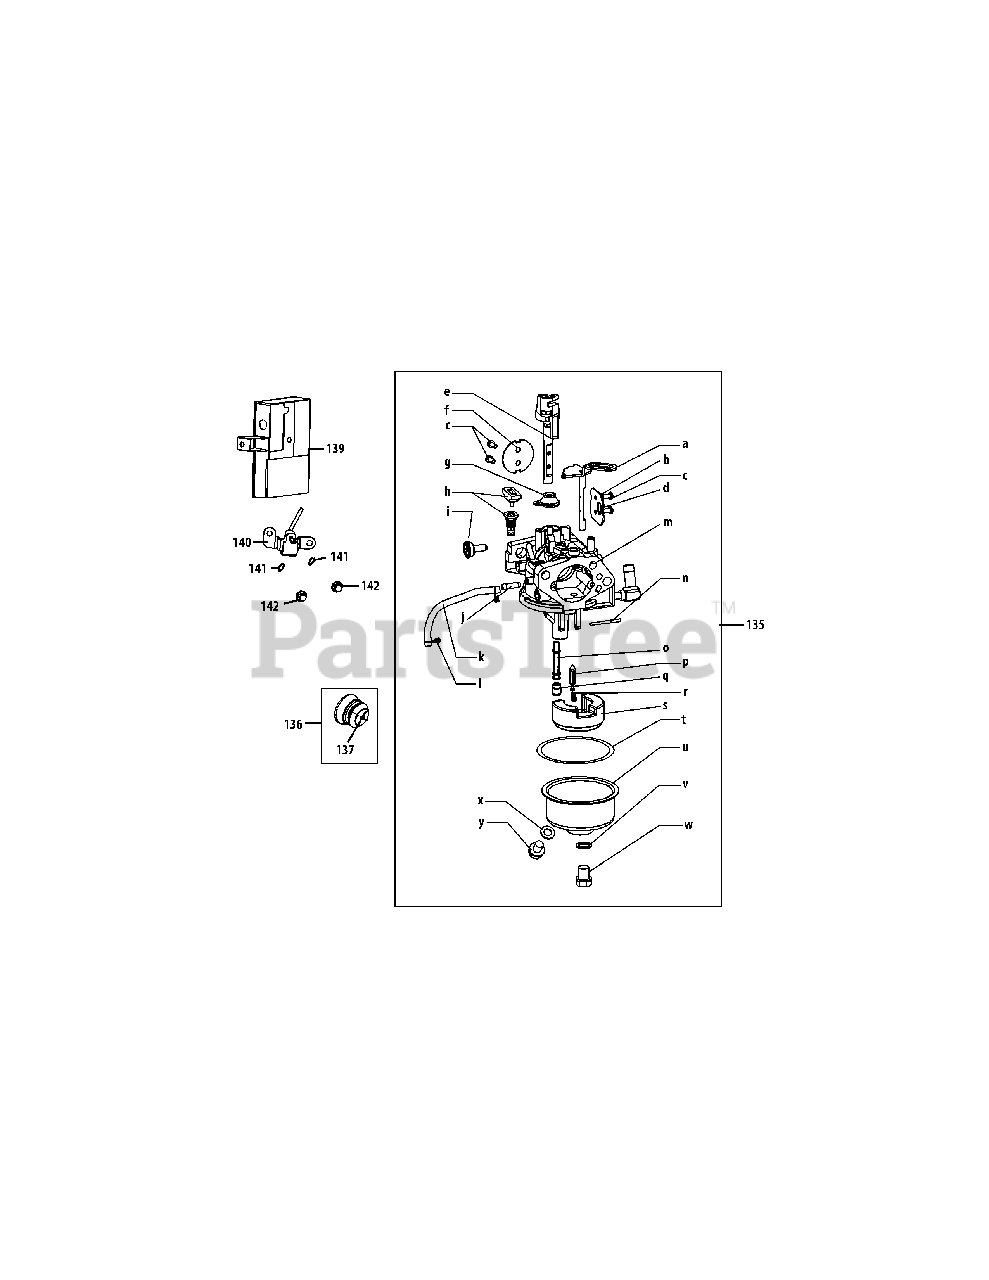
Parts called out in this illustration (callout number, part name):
135	Carburetor Assembly
136	Primer Assembly
137	Primer Bulb
139	Heater Box
140	Choke Assembly
141	Lock Washer
142	Nut M6
